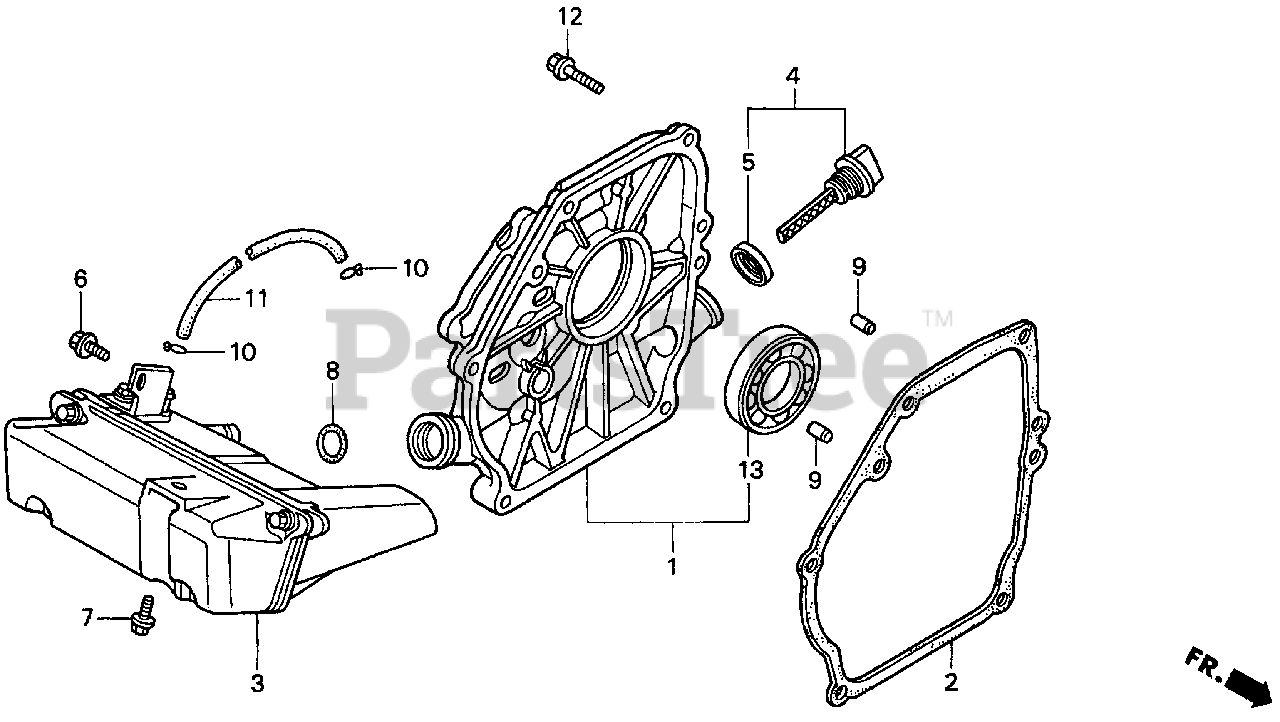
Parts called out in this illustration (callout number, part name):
1	COVER ASSY., CRANKCASE
2	GASKET, CASE COVER
3	TANK ASSY., OIL
4	CAP ASSY., OIL FILLER
5	GASKET, OIL FILLER CAP
6	BOLT, FLANGE (6X14)
7	BOLT, FLANGE (6X16)
8	O-RING (15.8X2.4) (SHOWA)
9	PIN C, DOWEL (8X14)
10	CLIP, TUBE (B7)
11	BULK HOSE, VACUUM (3.5X8000) (3.5X130)
12	BOLT, FLANGE (8X32)
13	BEARING, RADIAL BALL (6205)
